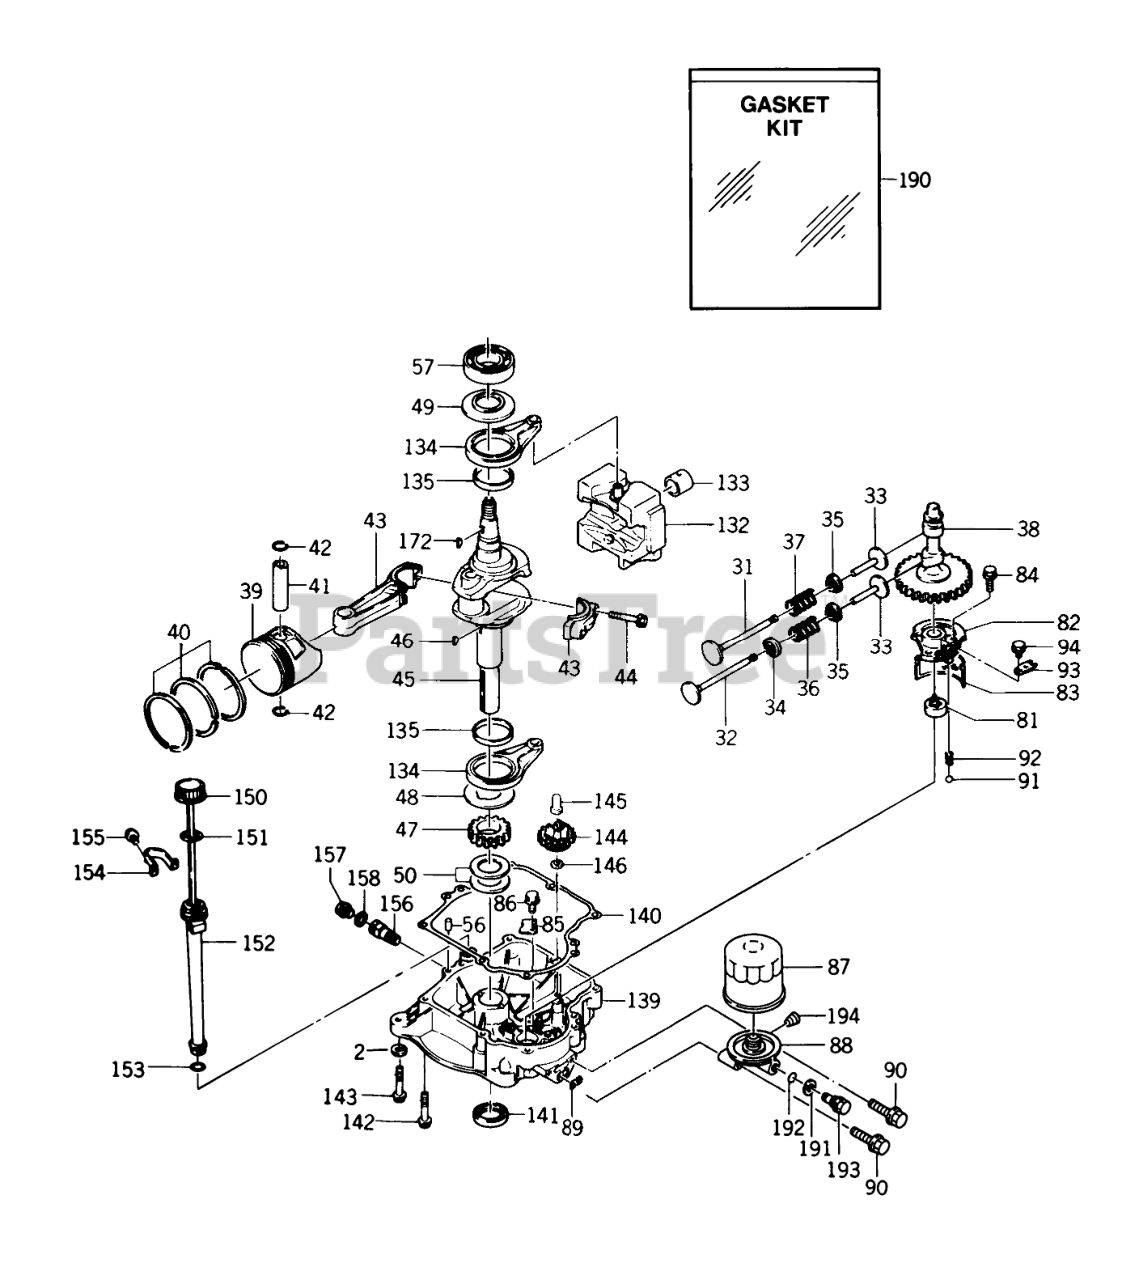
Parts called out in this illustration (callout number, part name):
2	WASHER 5/16 SAE
31	VALVE-INTAKE
32	VALVE-EXHAUST
33	TAPPET-VALVE
34	ROTATOR-VALVE
35	RETAINER-VALVE
36	SPRING-VALVE
37	SPRING-VALVE
38	SHAFT-CAM
39	PISTON-(STD)
40	RING (STD)
41	PIN-PISTON
42	RING-SNAP
43	Connecting Rod Assty - Standard (includes item 44)
44	BOLT-CON ROD
45	Crankshaft Complete
46	KEY-WOODRUFF
47	GEAR-HELICAL
48	SPACER
49	SPACER
50	SHIM-T=1.18
57	BEARING-BALL #6207
81	PUMP OIL
82	COVER-PUMP
83	FILTER-INTERNAL OIL
84	BOLT, FLANGED 8X25
85	PLATE
86	Bolt
87	OIL-FILTER KMC
88	Bracket (includes item 194)
89	RING O
90	BOLT-FLANGED
91	BALL-STEEL 5/16
92	SPRING
93	PLATE
94	BOLT-FLANGED
132	Weight Complete (includes item 133)
133	BEARING-PLAIN
134	Rod Assy (includes item 135)
135	BEARING PLAIN
139	COVER-CRANKCASE
140	GASKET
141	SEAL OIL
142	BOLT-FLANGED
143	BOLT, FLANGED 8X25
144	GOVERNON
145	SLEEVE-GOVERNOR
146	WASHER
150	GAUGE-OIL
151	GASKET
152	FILLER
153	O-RING
154	CLAMP
155	Bolt
156	JOINT
157	PLUG DRAIN
158	GASKET
172	KEY-WOODRUFF
190	GASKET SET-OVERHAUL
191	GASKET
192	O'RING
